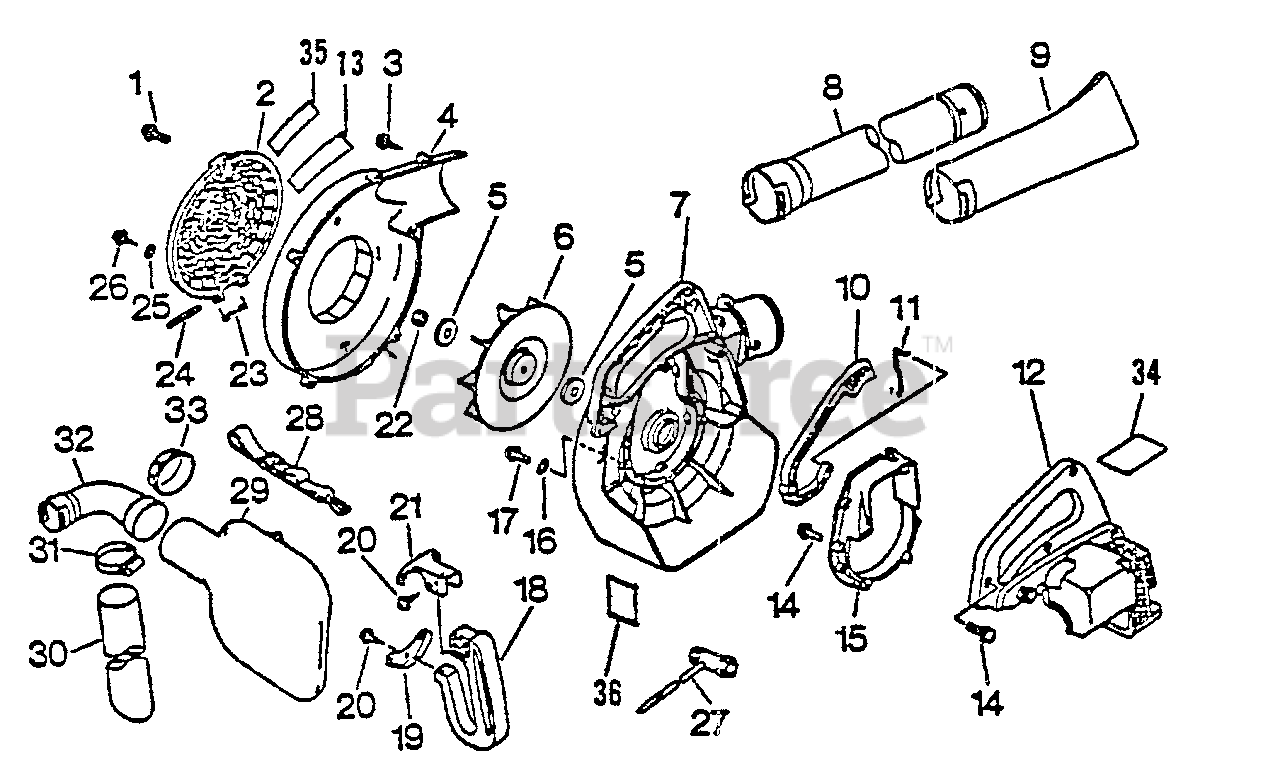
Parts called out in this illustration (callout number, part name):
1	SCREW - 5X18
2	GUARD, DEBRIS
3	SCREW - 5X20 -- TAPPING
4	COVER, FAN - LEFT
5	WASHER - 8
6	FAN
7	COVER, FAN - RIGHT
8	TUBE, BLOWER - STRAIGHT
9	NOZZLE - FAN HEAD
10	TRIGGER, THROTTLE
11	ROD, THROTTLE
12	COVER, ENGINE
13	LABEL - MODEL
14	SCREW - 4X18
15	BRACKET, ENGINE
17	SCREW - 4X22
18	HANDLE
19	SUPPORTER, HANDLE
20	SCREW - 5X14
21	SUPPORTER, HANDLE
26	SCREW - 5X14
27	T-WRENCH - 13X19mm
28	HARNESS
29	BAG
30	ADAPTER, PIPE
31	CLAMP, FLEXIBLE PIPE
32	CONNECTOR
33	RING
34	LABEL - HOT SURFACE
35	LABEL - NOISE
36	LABEL - NOISE
